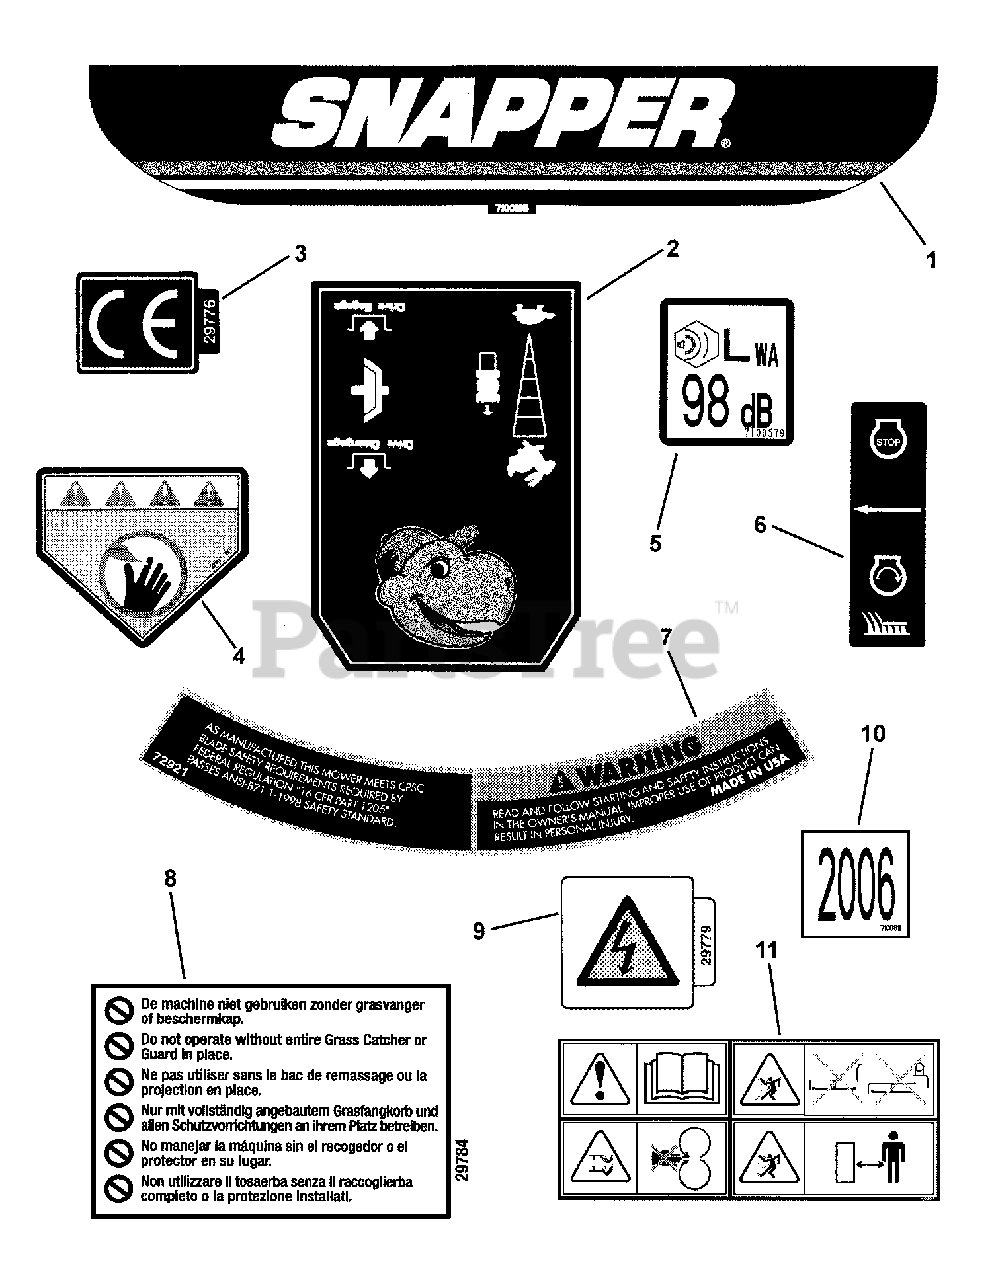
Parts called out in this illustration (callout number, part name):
1	DECAL, SNAPPER, Steel Decks
2	DECAL, Control Head, Variable Speed
3	DECAL,Euro Community (CE)
4	DECAL, Warning (Euro)
5	DECAL, Noise, 98 DB
6	DECAL, OPC Bail International Symbol
7	DECAL, Warning (Deck)
8	DECAL, Deck/Chute International Warning
9	DECAL, Spart Plug International Symbol
10	DECAL, 2006 Year of Manufacture
11	DECAL, Warning, Euro, Multi-Panel
